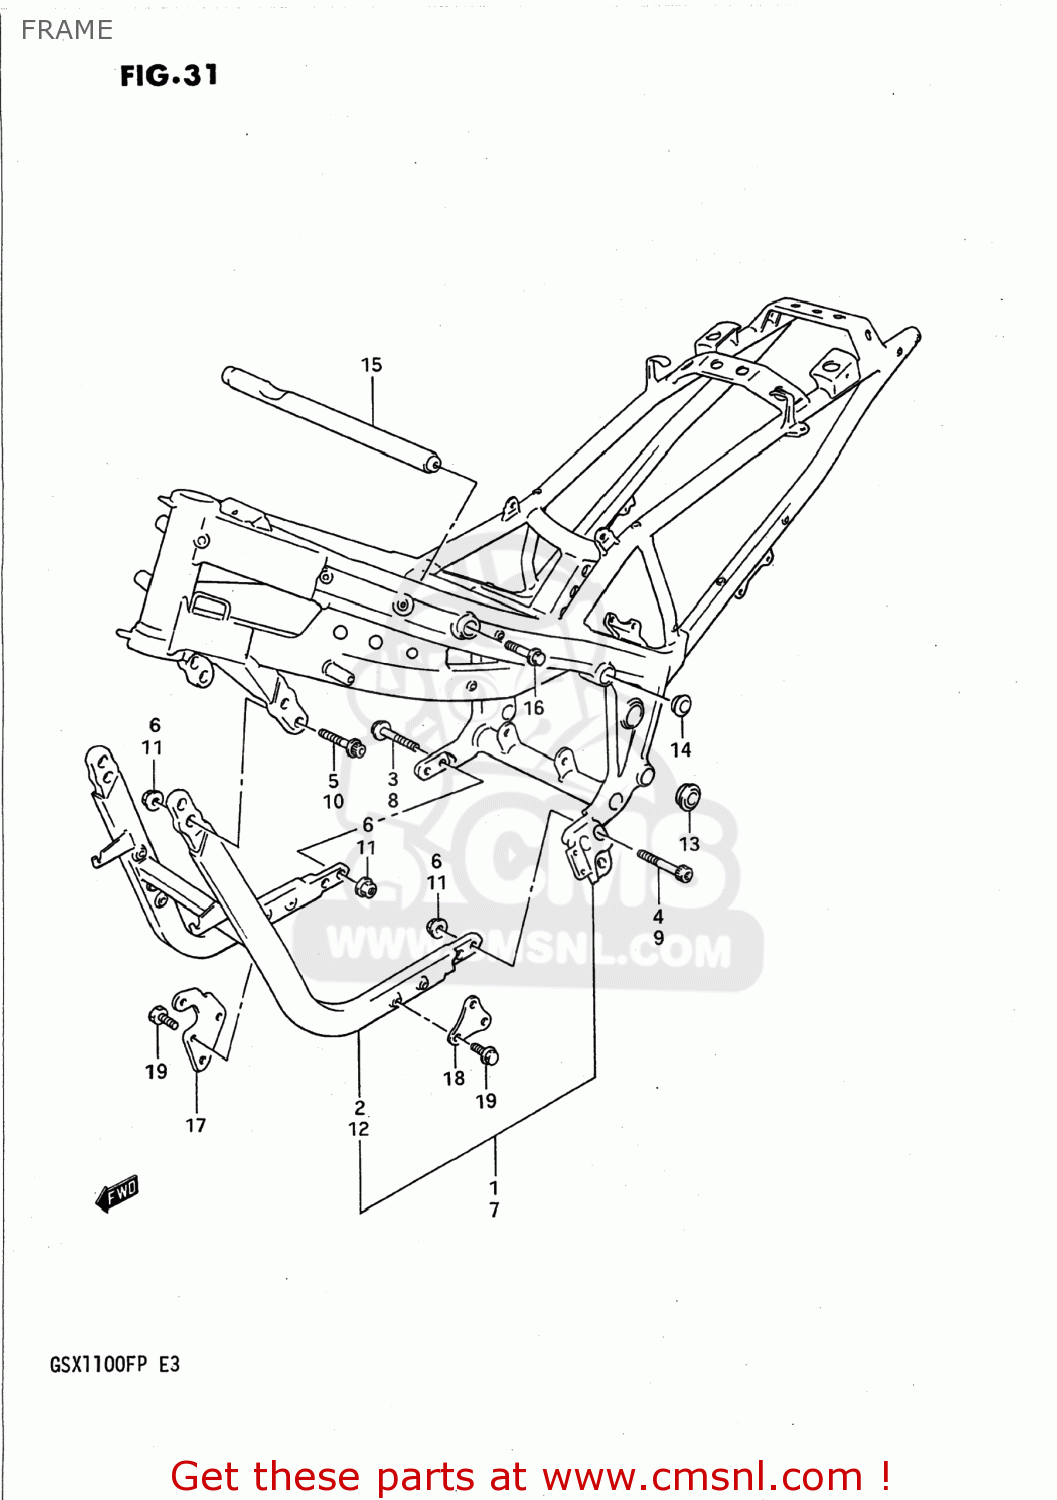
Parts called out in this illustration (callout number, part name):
1	FRAME
2	TUBE,FRAME,DOWN
3	BOLT,REAR RH
4	BOLT,REAR LH
5	BOLT,FRONT
6	NUT
7	FRAME
8	BOLT
9	BOLT
10	BOLT
11	NUT
12	TUBE,FRAME,DOWN
13	CAP,FRAME NO.1
14	CAP,FRAME NO.2
15	BRIDGE,TANK RAIL
16	BOLT,TANK BRIDGE
17	PLATE,ENGINE MOUNTING
18	PLATE,ENG MTG NO.2
19	BOLT
